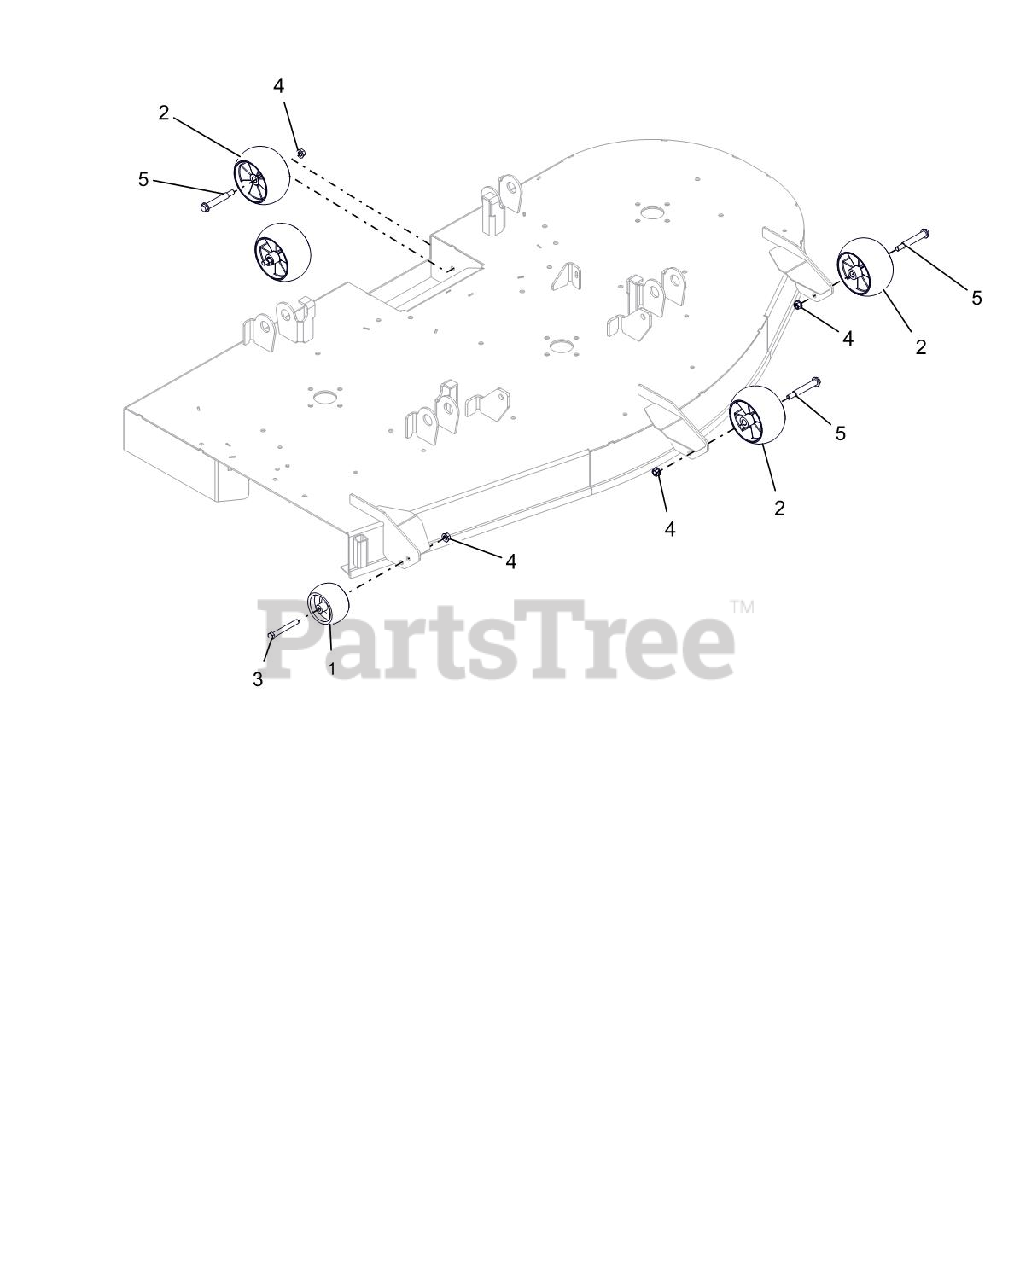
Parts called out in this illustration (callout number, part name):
2	ANTI-SCALP WHEEL - 5X OS
3	BLT-HEX .38-16X3.00 HEX 8 YWZC
4	@NUT-LK-TOP-FLG .38-16 YWZC
5	BLT-SHLDR .38-16X2.50 HWH G5
